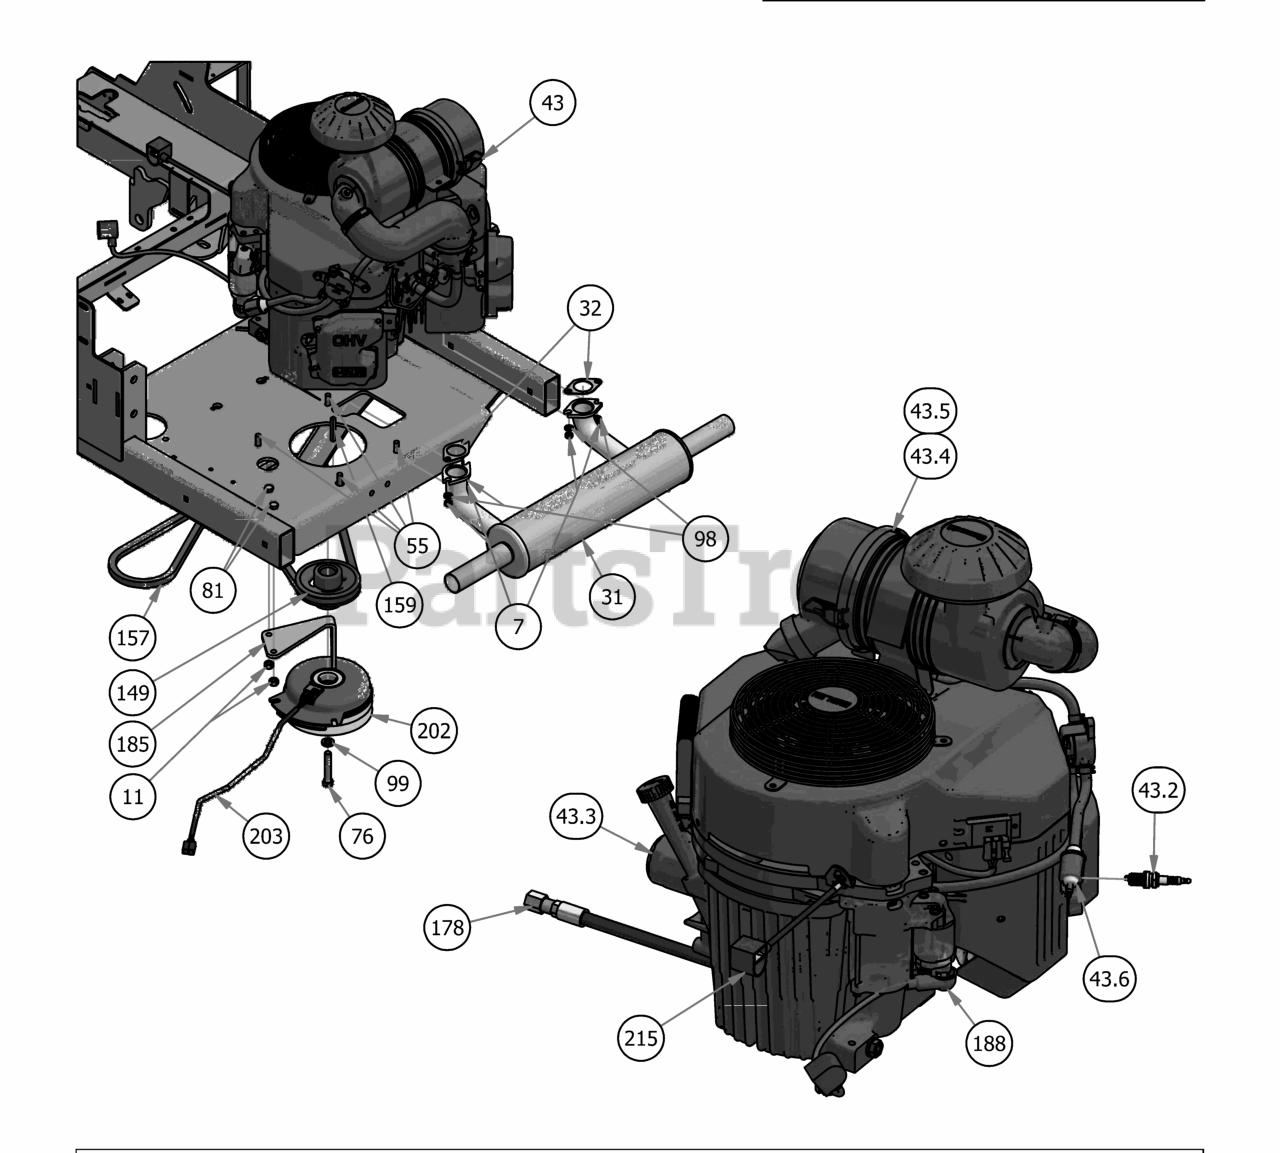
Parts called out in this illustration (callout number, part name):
7	M8-1.25 Zinc Nut
11	3/8" Hex Nut
31	Muffler for Kawasaki FX1000
32	Exhaust Gasket
43	Kawasaki FX1000 Engine
43.2	Spark Plug - Kawasaki
43.3	Oil Filter
43.4	Canister Air Filter- Inner
43.5	Canister Air Filter- Outer
43.6	Universal Inline Fuel Filter
55	3/8 x 1 1/8 bolt
76	7/16" x 2 1/2" Hex Bolt
81	3/8" x 1" Hex Bolt
98	5/16" Lock Washer
99	7/16" Lock Washer
149	4 3/4 Motor Pulley
157	2019 Rogue Pump Belt 68"
159	1/4 x 2 Square key Stock
178	Kawasaki Oil Drain
185	PTO Engager Holder
188	24" Red Battery Cable
202	Clutch Assembly
203	Clutch Pigtail
204	2019 Veritical Suspension Frame
215	Starter Cable
217	Kawasaki Harness Adapter
